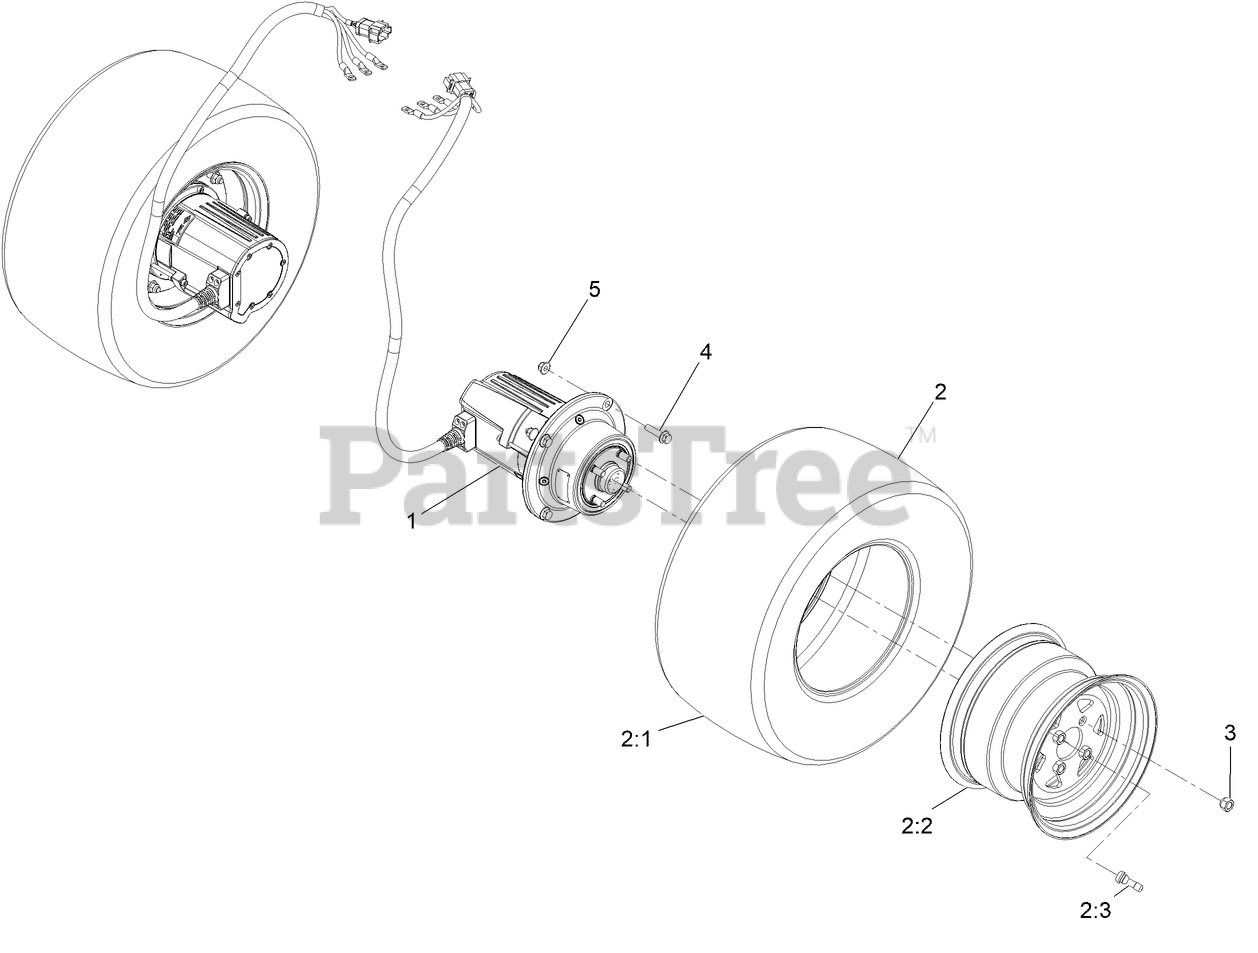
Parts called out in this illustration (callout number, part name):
1	MOTOR/GEARBOX ASM-48V,
2	WHEEL AND TIRE ASM
2:1	RIM-10 IN
2:3	Stem-Valve
3	NUT-WHEEL
4	SCREW-HHF
5	NUT-HF, NI
